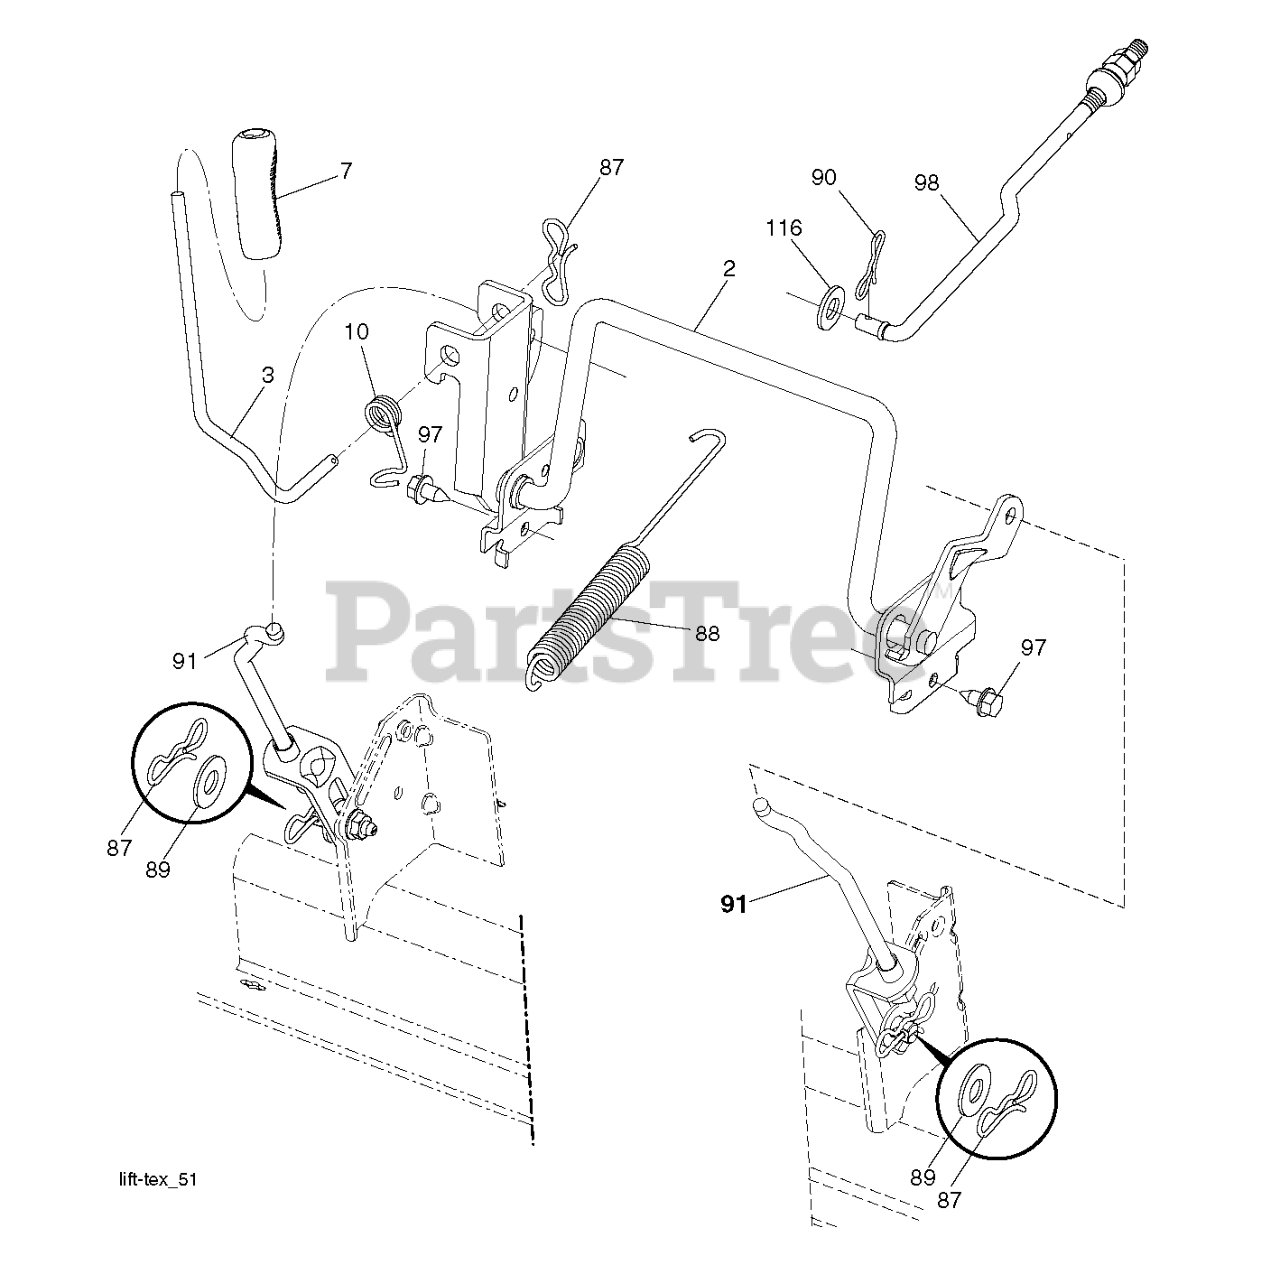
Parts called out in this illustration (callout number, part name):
2	SHAFT LIFT DECK WELD
3	Levers
7	GRIP.HANDLE.LIFT.PVC.BLACK
10	SPRING.TORSION.LIFT.HANDLE
87	PIN.COTTER.7/16.BOW TI.
88	SPRING.DK.LIFT.97/107.TXCRDII
89	WASHER.CLEAR.ZINC
90	PIN.COTTER.5/16.BOW TI
